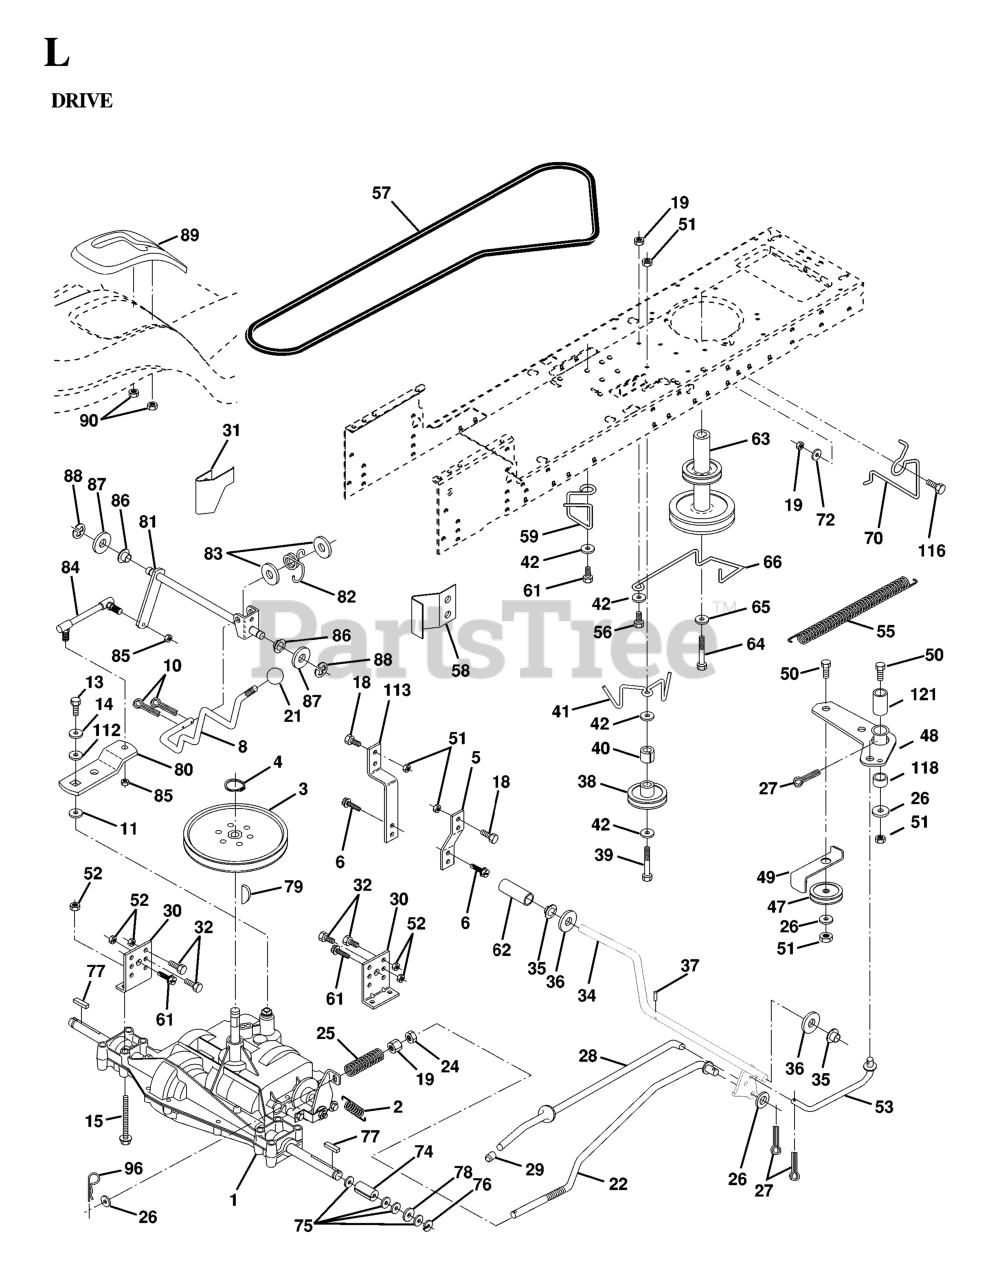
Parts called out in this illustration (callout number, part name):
1	TRANSAXLE NLA
2	SPRING,BRAKE RETURN
3	PULLEY TRANS
4	RETAINING RING LT
5	STRAP TORQUE
6	SCREW.THDROL.5/16-18X3/4.TTY
8	ROD SHIFT FENDER
10	PIN COTTER
11	WASH-SHFT PLT LT
13	BOLT 1/4-28X3/4
14	LOCKWASHER
15	BOLT HEX 5/16-18 GR 5
19	NUT
21	KNOB.DUCKHEAD.1/2
24	NUT
25	SPRING ROD LT
26	WASHER
27	COTTER PIN
28	ROD BRAKE PARK LT
29	PLUNGER CAP
30	BRACKET TRANSAXLE
31	KEEPER BELT LH
32	BOLT
34	SHAFT, FOOT PEDAL
35	BEARING.NYLON
37	DRIVE PIN
38	PULLEY.IDLER.FLAT
41	KEEPER, BELT IDLER
42	WASHER
47	IDLER PULLEY
48	BELLCRANK ASSEMBLY
49	RETAIN BELT
50	BOLT
52	LOCKNUT
53	LINK, CLUTCH LT
55	SPRING, RETURN LT
59	KEEPER CENTER SPAN
61	SCREW
62	COVER, PEDAL (1 2)
63	PULLEY.ENG.CL.MECH.SLVR.LT/YT
64	BOLT
65	LOCKWASHER
66	KEEPER BELT ENGINE
70	KEEPER BELT ENG
72	WASHER
74	SPACER AXLE
77	SQUARE KEY
79	KEY STD (1373) DANA
81	SHAFT ASM CROSS 20"
82	SPRING,TORSION
83	WASHER
84	ROD TIE 20"
85	NUT LOCK CENTER 1/4 -28 FNTHD
86	BUSHING.STEERING.ROD LTB-WSL
89	CONSOLE SHIFT
90	NUT.PUSH.3/16
96	RETAINER M
113	STRAP TORQUE LH LT
116	BOLT
118	SPACER BELLCRANK
121	NYLINER CLUTCHING
